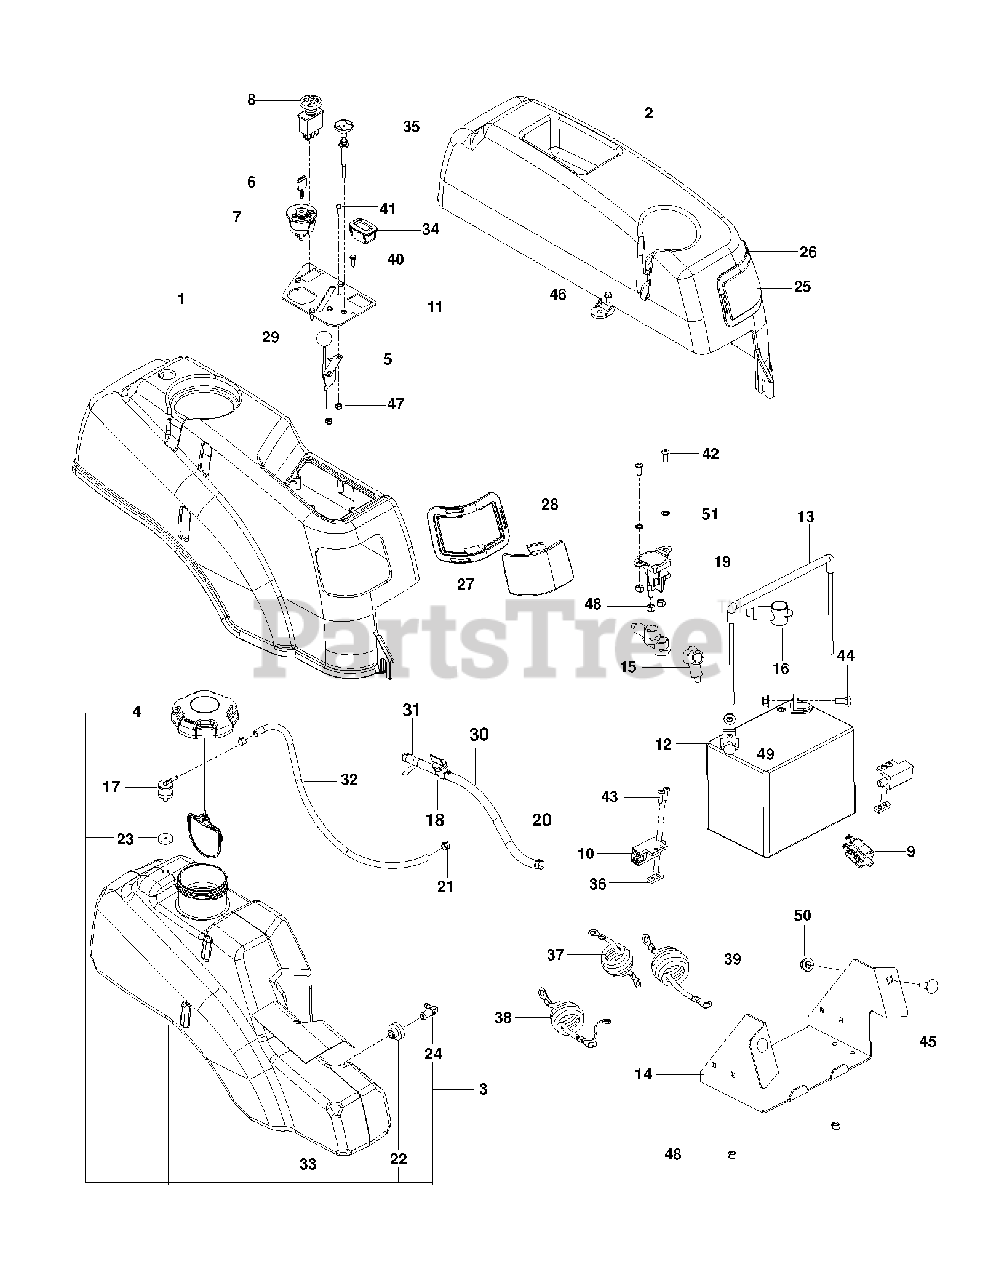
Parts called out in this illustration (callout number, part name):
1	FENDER RT, GRAY
2	FENDER, LT
3	TANK.FUEL.ASSEMBLY.LARGE
4	CAP, FUEL
5	THROTTLE CABLE
6	KEY MLD GEN DELTA
7	RP IGNITION SWITCH
8	RP SWITCH.PTO.8.TERMINAL.RED
9	SWITCH, BRAKE 3P
10	SWITCH INTERLOCKT
11	CONSOLE.PLATE.BLACK
12	BATTERY, 12 V 330 AMP
13	BATTERY TIE DOWN ASSEMBLY
14	BOX, BATTERY, BLACK
15	TERMINAL COVER-SM
17	VALVE.FUEL.CHECK
18	FUEL VALVE
20	HOSE CLAMP
21	CLAMP, HOSE
22	RUBBER GROMMET
23	GROMMET, CHECK VALVE
24	STEM, FUEL TANK
25	LENS, COLORED LEFT
26	LEFT HEADLIGHT RIM GREY
27	LENS, COLORED RIGHT
28	RT HEADLIGHT RIM GREY
29	KNOB.ROUND.BALL.BLACK
30	GAS LINE 10"
31	FUEL LINE 3"
32	HOSE, FUEL, 3/16" X 20"
33	SHIELD, HEAT
34	HOUR METER
35	CHOKE CABLE
36	TAPPED PLATE
37	CABLE POSITIVE, LONG
38	CABLE POSITIVE LONG W/LEAD
39	BATTERY CABLE, NEGATIVE
40	SCR #10-12X3/4 HEX WAS HD ZD
41	HCS #10-24 X 1/2
42	SCR 1/4-20 X 5/8 BTN SKT HD ZD
43	SCR #10-24 X .75 SKT HD BLK
44	BOLT 5/16C X 3/4" CARRIAGE
45	RHSNB 3/8C X 1
46	BOLT 1/4-20 X 1/2 HWST
47	NUT 10-24 NYLOC
48	RP_NUT 1/4-20 NYLOC
49	5/16-18 NYLOC FLANGE NUT
50	NUT 3/8-16 HEX FLG NYLOC ZD
51	WASHER 1/4 INT TOOTH
